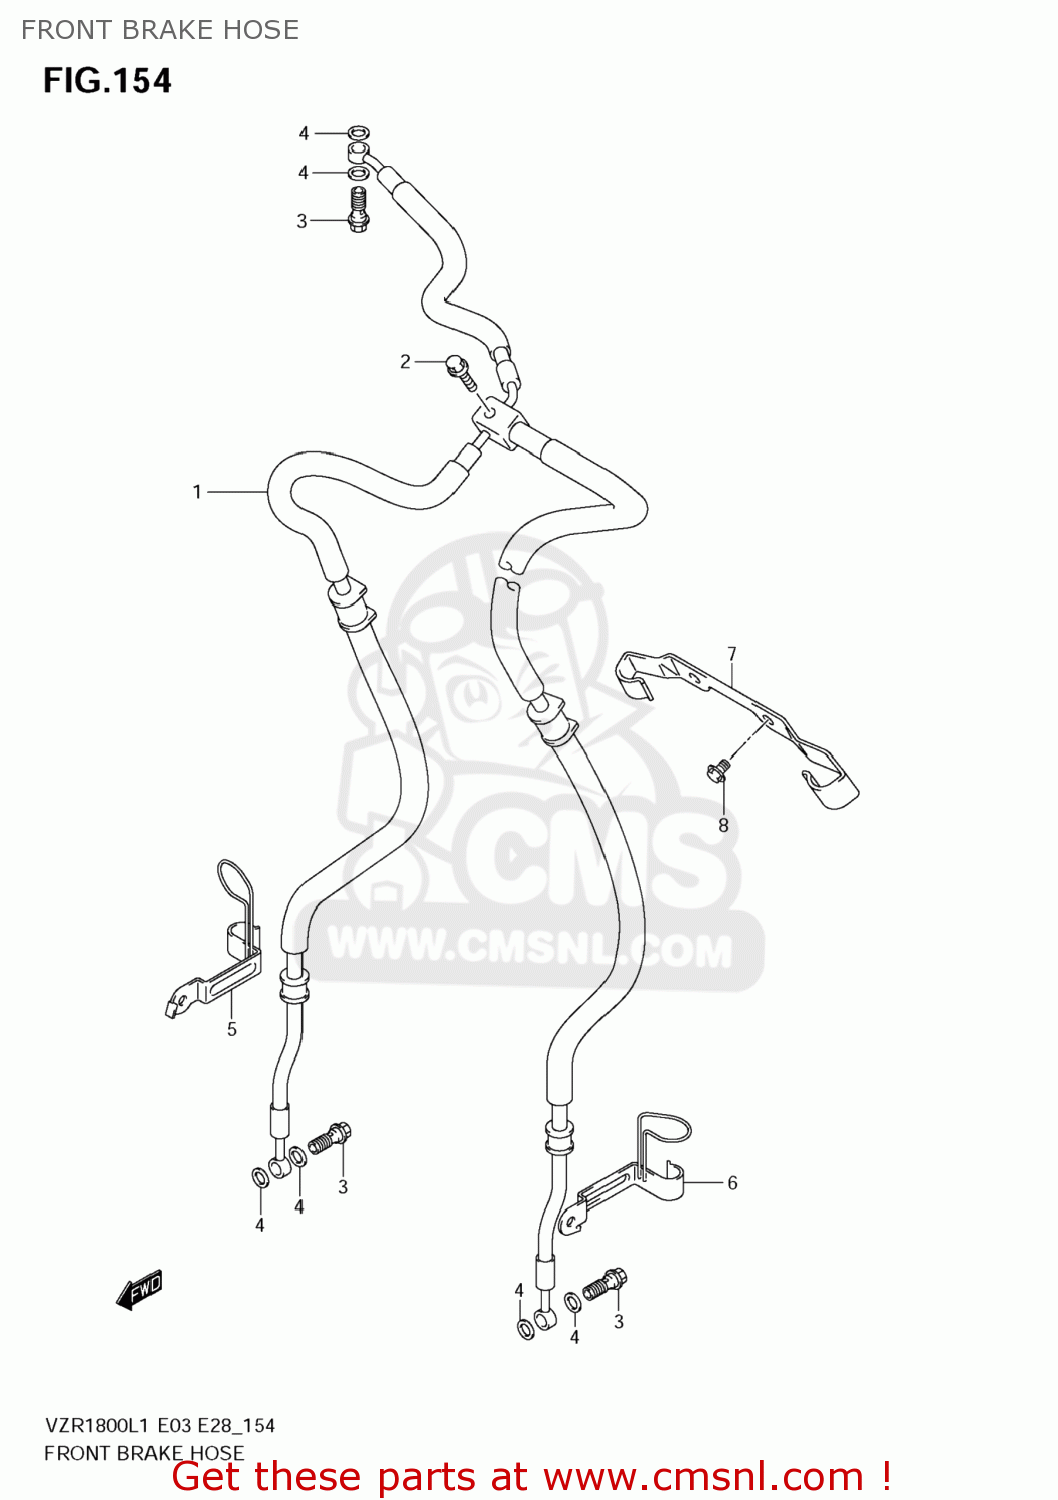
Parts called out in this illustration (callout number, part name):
1	HOSE,FR BRAKE
2	BOLT
3	BOLT UNION
4	WASHER(10X15X1.5)
5	CLAMP,FR BRAKE HOSE,R
6	CLAMP,FR BRAKE HOSE,L
7	CLAMP,FR BRAKE HOSE
8	BOLT
